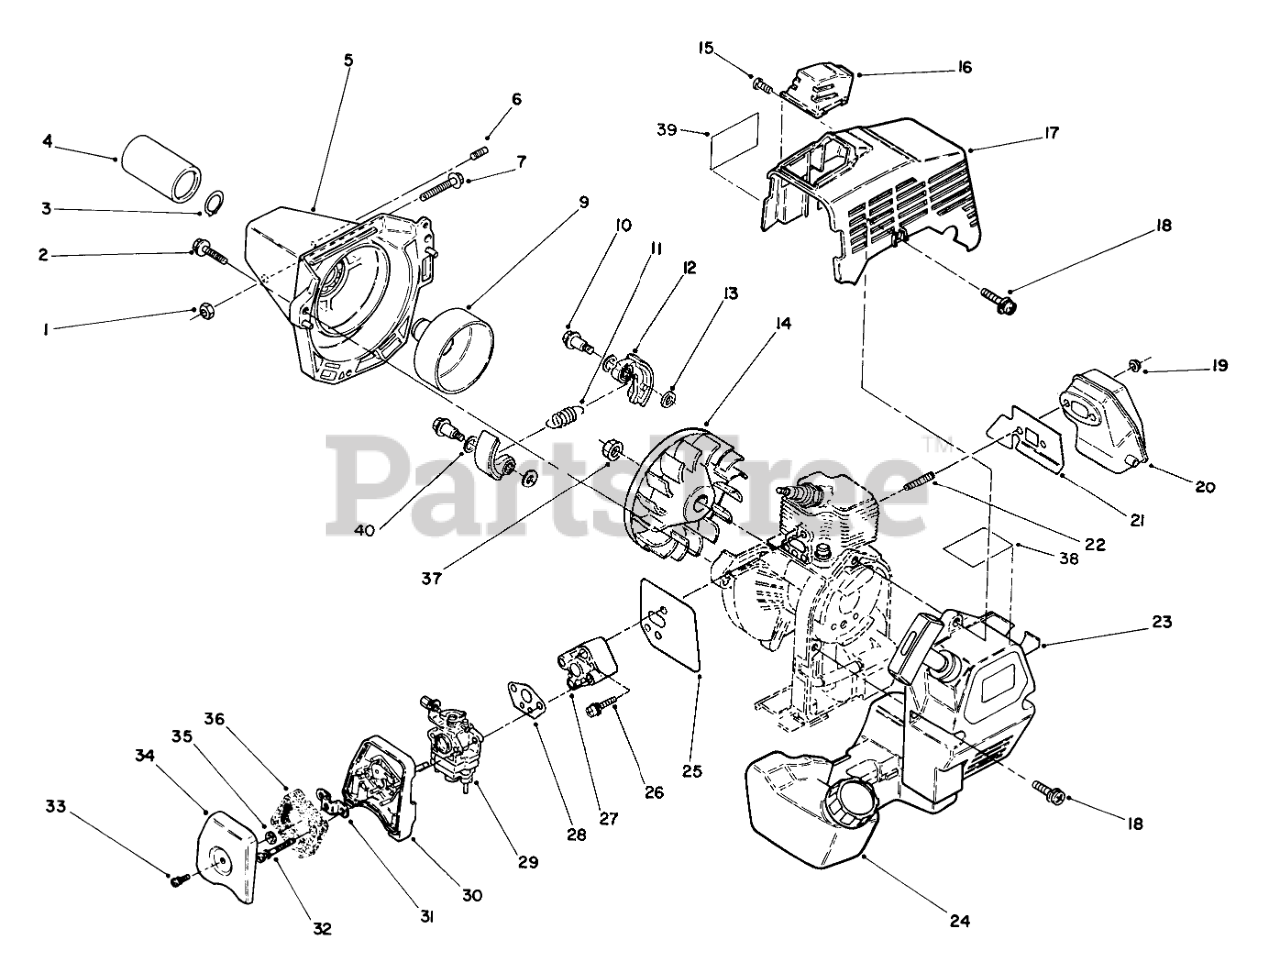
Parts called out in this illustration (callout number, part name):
2	BOLT AND WASHER
3	SNAPRING
4	Spacer
5	Housing-Clutch
6	SETSCREW
7	Screw/Washer
9	CLUTCH DRUM
10	CLUTCH BOLT
11	Spring
12	SHOE, CLUTCH
13	WASHER
14	Fan
15	SCREW & WASHER
16	SPARK PLUG GUARD
17	TOP SHIELD
18	SCREW & WASHER
19	MUFFLER FLANGE NUT
20	MUFFLER
21	MUFFLER GASKET
22	MUFFLER STUD
23	RECOIL ASSEMBLY
24	FUEL TANK ASM
25	INSULATOR GASKET
26	SCREW & WASHER
27	INSULATOR
28	CARBURETOR GASKET
29	CARBURETOR ASM
30	CLEANER CASE
31	BRACKET
32	SCREW W/ WASHER
33	SCREW & WASHERE
34	CLEANER COVER
36	CLEANER ELEMENT
38	Decal-Fuel Mix
39	DECAL-SURFACE, HOT
40	SPRING WASHER
